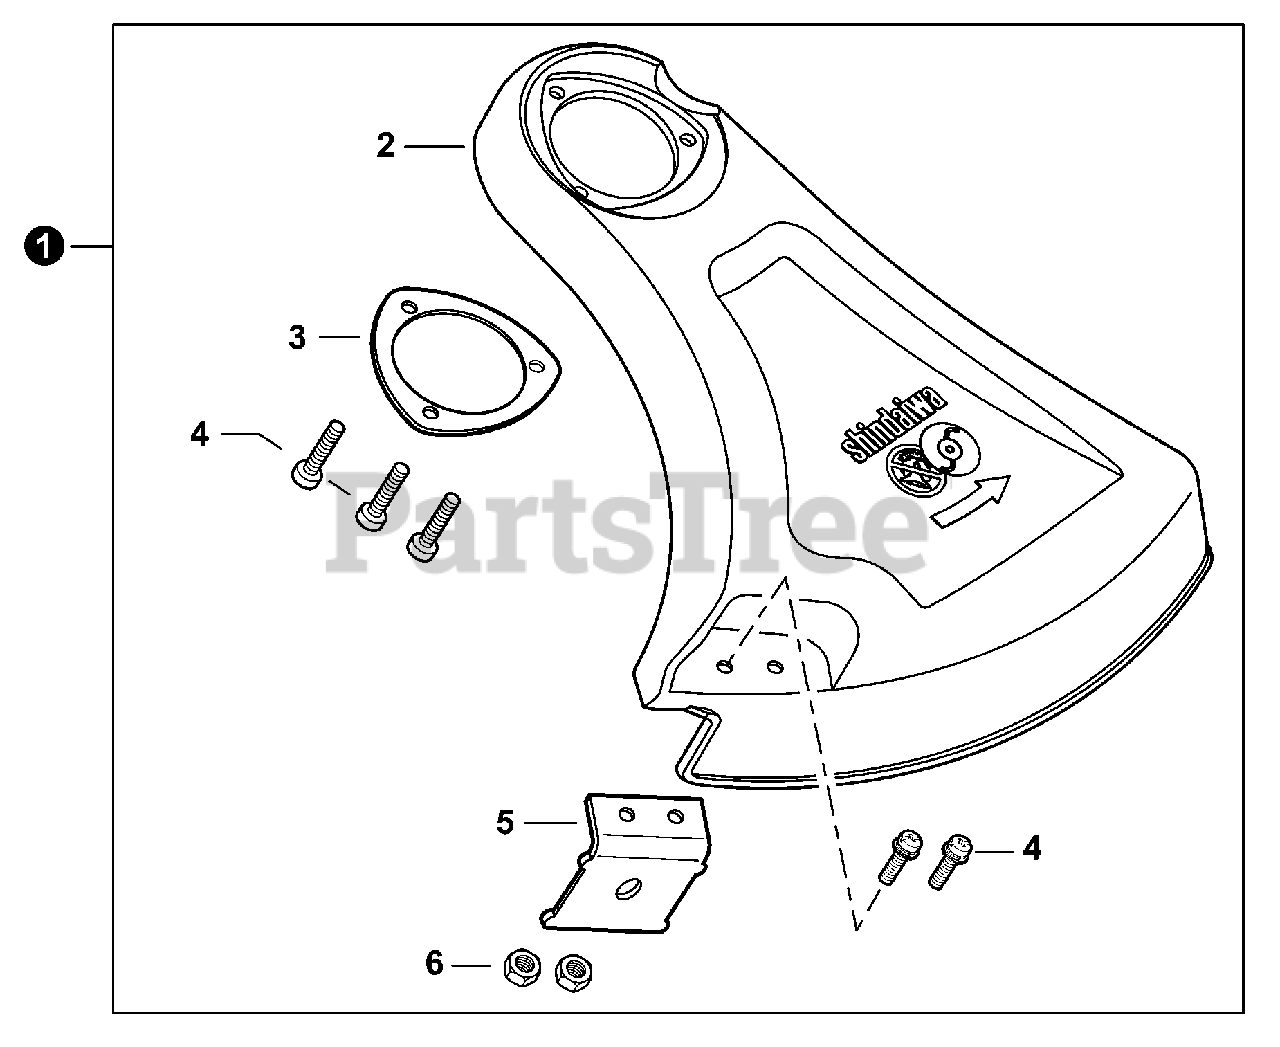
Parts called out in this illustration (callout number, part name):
1	DEBRIS SHIELD ASSY
2	SHIELD, DEBRIS
3	PLATE, SHIELD Ø49.5 MM
4	SCREW 5×16
5	CUTTER, LINE
